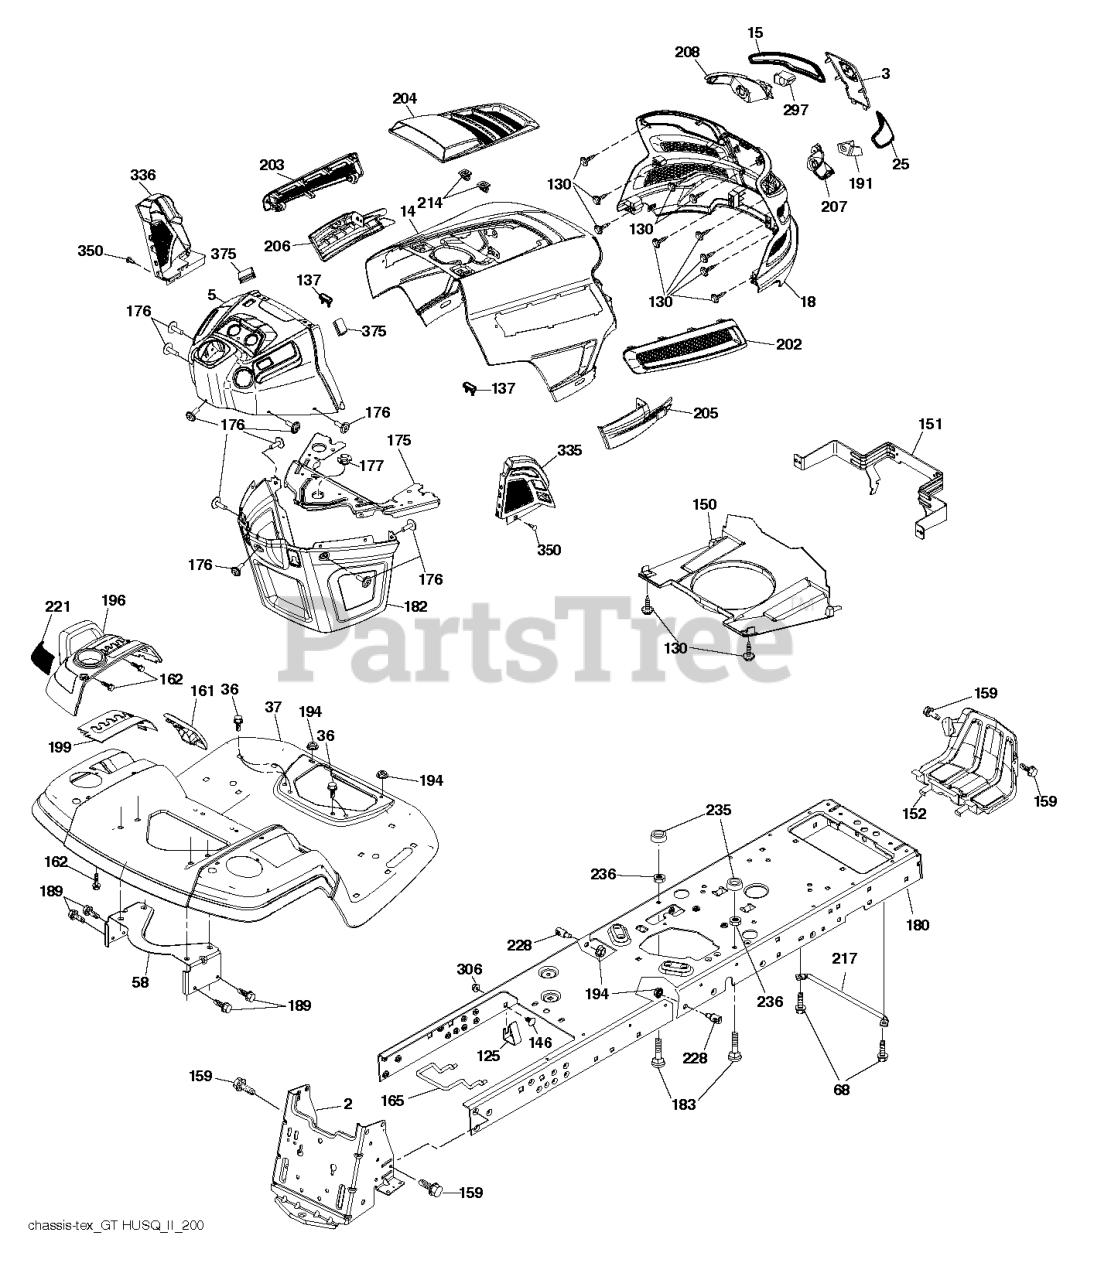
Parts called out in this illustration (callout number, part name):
2	DRAWBAR.STGT
3	APPLIQUE.SUBASM.GT.HUSQ.II
5	DASH.UPP.GT2.DUAL.RD.PTO.MCHOK
14	HOOD.ASM.HUSQVARNA.GT.TEX.ORAN
15	LENS.HEADLIGHT.LH.GTII.2011
18	GRILLE.SUBSTRATE.2011.
25	LENS.HEADLIGHT.RH.GTII.2011
36	SCREW 5/16"
37	FENDER.PNT.TX.GT.CH/FW/DL.HUSQ
58	BRKT.SUPPORT.FNDR/TANK
68	Screw 5/16-18 x 1/2 Hex, Self Tapping 5/16-18 x 1/2
125	CLIP.FUEL.LINE
130	SCREW.#10 X 0.750.BOS
137	BUMPER DASH
146	BOLT.RDHD.SHT.SQNK.3/8-16X5/8
150	AIR.DUCT.GTV.BLACK
151	BRACKET.PIVOT.HOOD.GT.HUSQ.II
152	SHIELD.BROWNING.PNT.GT.V2
159	SCREW, 3/8-16X3/4
161	CONSOLE.WINDOW.FUEL.HUSQ.GT
162	SCREW.HI-LO.CONSOLE
165	SUPPORT.TANK.REAR.B/TE
175	PLATE.CROSSMEMBER.HUSQ
176	SCREW.#10-24X5/8.RN.QU
177	BUSHING STEERING
180	CHASSIS.TEX.BOLTED
182	DASH.LOWER.COMMON.12V.ADAPTOR
183	BOLT.5/16-18X1-1/4 FULL THD
189	SCREW
191	INSERT.REFLECTIVE.RH.HUSQ.GTII
194	NUT LOCK HEX FLANGE 5/16-18
196	CONSOLE.ASM.DECKLIFT.HUSQGT.DL
199	PLATE.DECK.LIFT.HUSQVARNA.GT
202	VENT.SIDE.RH.GT.HUSQ.II.
203	VENT.SIDE.LH.GT.HUSQ.II.498
204	VENT.TOP.HUSQ.GT2
205	SIDE.TRIM.RH.GT.HUSQ.II
206	SIDE.TRIM.LH.GT.HUSQ.II.GRAY
207	BEZEL LIGHT.RH.GT.II.MYLAR
208	BEZEL LIGHT.LH.GT.II.MYLAR
214	CLIP.RETAINER.TINNER.
217	ROD.PIVOT.HOOD
221	REFLECTOR.LH.TEX GT HU
228	STUD.FASTNER.W/ANTI-ROTATE
235	SPACER FENDER
236	NUT.CENTERLOCK.5/16-
297	INSERT.REFLECTIVE.LH.HUSQ.GTII
306	NUT LOCK FLG 3/8-16 UNC
335	COVER.LOWER.DASH.RH.BLACK
336	COVER-LH.LOWER.DASH.GT2.BLACK
350	CLIP.X-MAS.TREE
375	BUMPER CLIP-ON. DASH 1"
